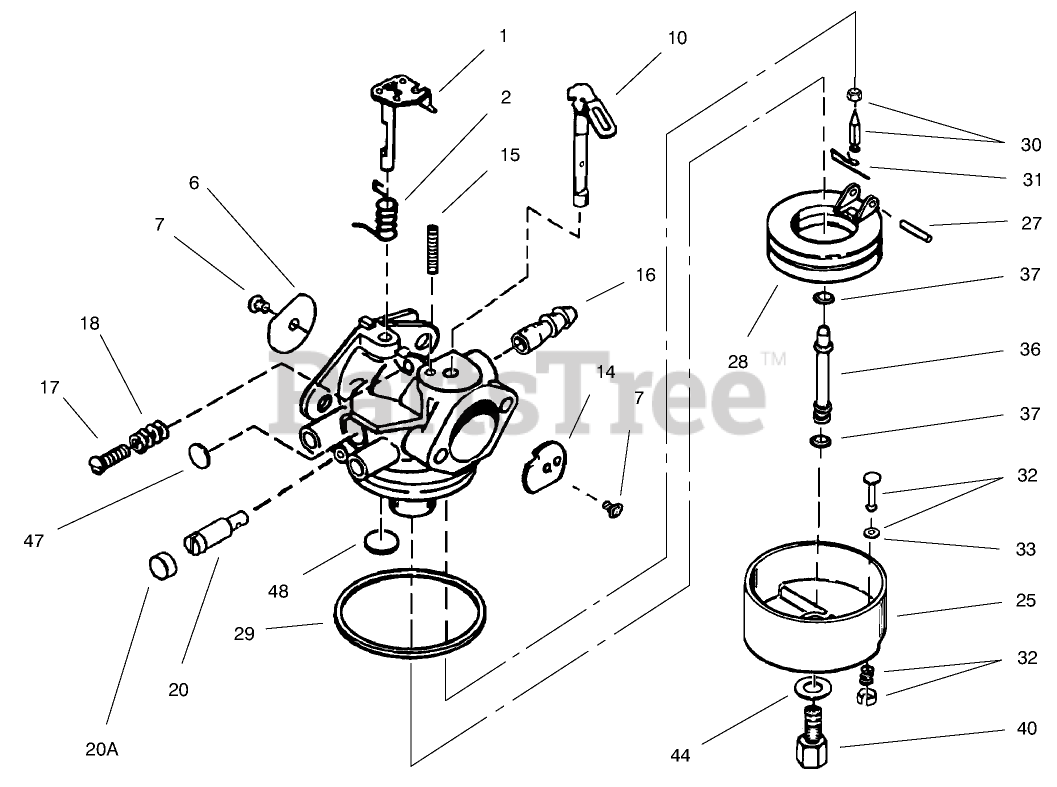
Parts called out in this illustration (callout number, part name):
1	Throttle Shaft and Lever ASM
2	Spring-Return, Throttle
6	Shutter-Throttle
7	Screw-Shutter
10	Choke Shaft and Lever ASM
14	Shutter-Choke
15	Spring-Positioning, Choke
16	Fitting-Fuel
17	Screw-Throttle Crack Screw / Idle Speed
18	Spring-Tension
20	Screw-Restrictor, Idle
20A	Cap-Screw, Idle Restrictor
25	Float Bowl Asm. (Incl. Ref. # 32, 33)
27	Shaft-Float
28	Float
29	O Ring-Bowl, Float
30	Inlet Needle, Seat Clip Assy. (Incl. No. 13)
31	Clip-Spring
32	Bowl Drain ASM
33	Gasket-Plunger, Drain
36	Tube-Nozzle, Main
37	O-Ring
40	Nut-High Speed, Bowl
44	Washer-Bowl Nut
47	Plug-Welch, Idle Mixture Well
48	Plug-Welch, Atmospheric Vent
60	Repair Kit
